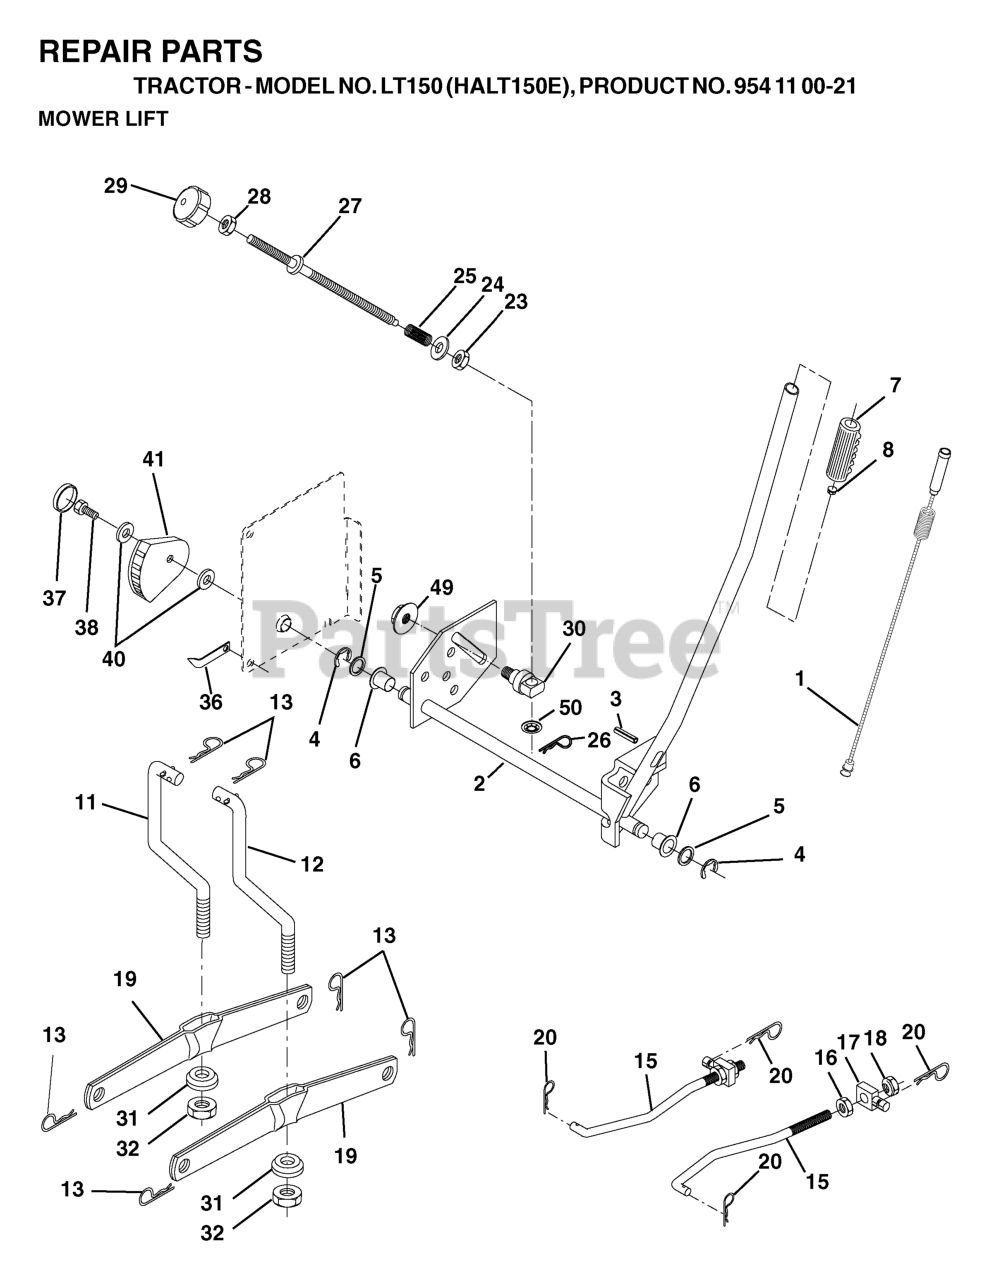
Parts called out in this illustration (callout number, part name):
1	WIRE ASM INNER W/ PLUNGER LT
2	SHAFT ASM R HANDLE
3	PIN GROOVE.
4	RETAINING RING LT
6	BEARING.NYLON
7	GRIP HANDLE
8	PLUNGER BUT KIT
11	LINK LIFT LH
12	LINK LIFT RH
13	RETAINER-SPRNG RB
15	LINK FRONT
16	NUT.HEX.JAM.1/2-13
17	TRUNION
18	NUT.LK.W/WSH.1/2.
19	ARM.REAR.SUSPENSION
20	SPRING RETAINER
25	SPRING**
26	RETAINER CLIP
27	ROD ADJ LIFT
28	NUT
29	KNOB INF 3/8-16
31	BEARING PIVOT
32	NUT CROWNLOCK 3/8-24
36	POINTER, HEIGHT INDICATOR(2 2)
38	SCREW 5/16-18X1
41	IND. HEIGHT STLT
49	NUT
50	NUT PUSH M
